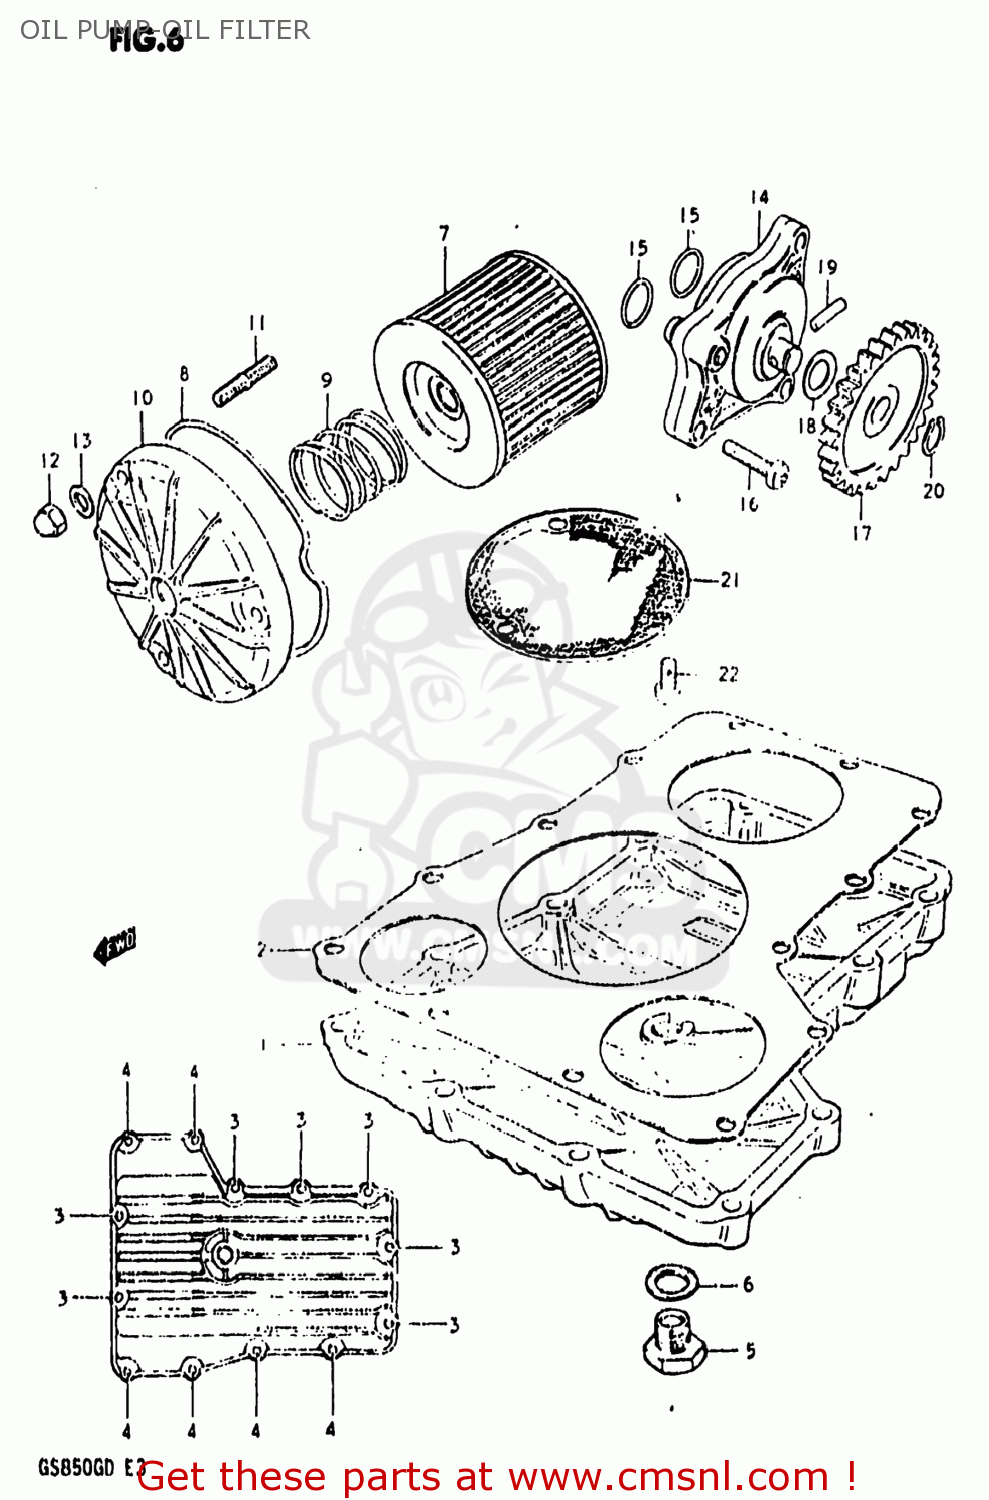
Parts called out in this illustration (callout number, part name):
1	PAN,OIL
2	GASKET,OIL PAN (MCA)
3	BOLT
4	BOLT
5	PLUG
6	GASKET(14X19.2X2) (NAS)
7	FILTER ASSY,ENGINE OIL
8	O RING,OIL FILTER CHAMBER CAP
9	SPRING
10	CAP,OIL FILTER
11	STUD 6X20
12	NUT
13	WASHER
14	PUMP ASSEMBLY,ENGINE OIL
15	O RING(D:1.9,ID:13)
16	SCREW
17	GEAR,ENG OIL PUMP DRIVEN(NT:33
18	SHIM
19	PIN(4X15.8)
20	CIRCLIP
21	STRAINER,ENGINE OIL
22	SCREW 6X12
